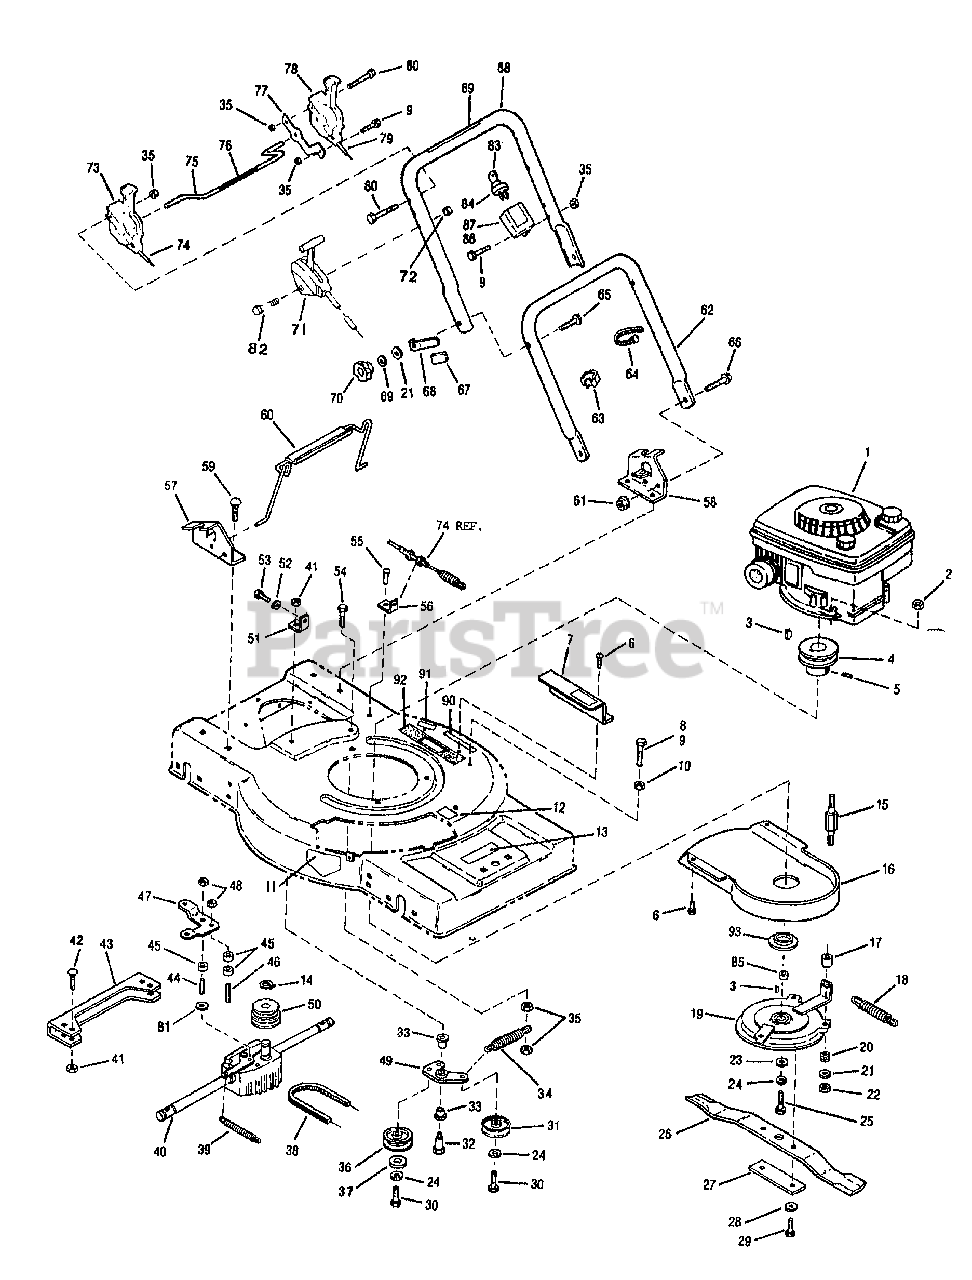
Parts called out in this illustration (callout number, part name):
1	ENGINE, B&S, 4HP MODEL 110707 STANDARD START
1	ENGINE, B&S, 4HP MODEL 110708 ELECTRIC START
2	NUT-FLANGE 5/16-18
3	KEY-WOODRUFF .156X.625
4	SHEAVE-ENGINE
5	SCR-SQHD 1/4-20X1/2 GR5
6	SCR-HW M10-24X.5 STH
7	COVER-SPRING ELEC. START
7	SPRING-CVR STD START
8	NUT-LK 1/4-20
9	SCR-HH 1/4-20X1.25
10	NUT-LK 1/4-20
11	DECAL-BLADE WARNING
12	DECAL-CAUTION
13	DECAL-CUTTING HEIGHT
14	RING, RETAINING
15	BOLT-SHOULDER-GR. 5
16	COVER-IDLER
18	SPRING-EXTENSION
20	SPRING-COIL
21	WASHER-.88X312X.08
22	NUT-H/LK 5/16-18
23	WASHER-FLAT 3/8 SAE
24	WASHER-LK .375
25	SCR-SKT HD 3/8-24X1.5 GR8
26	BLADE-VACUCUT
27	PLATE-LOCK
28	WASHER-LK .312 PYRAMIDAL (CONCAVE)
29	SCR-HFLK 5/16-18X.75
30	SCR-HH 3/8-16X1.25
31	IDLER-V
32	BOLT-SHLDR 5/16-18X.58
33	BUSHING-.5X.21 NYLON FLNG
34	SPRING-EXTENSION
35	NUT-LK 1/4-20
36	IDLER-FLAT
37	WASHER-FLAT 3/8 SAE
38	BELT-V (VACU-CUT) (33.87)
39	SPRING, EXTENSION
40	TRANSMISSION
41	NUT-HFLK 5/16-18
42	BOLT, CARRIAGE, 5/16-18 x 1-3/4" GR5
43	CHANNEL-REAR AXLE
44	STUD-THRD SHORT 10-24X1.00 G5
46	STUD-THRD LONG
47	TRANSMISSION-BRACKET
48	NUT-HEX M10-24
49	ASSM-ARM IDLER
52	WASHER-LK .25
53	SCR-HH 1/4-20X.625 G5
54	SCR-HH 1/4-20X1.0
55	RIVET-POP 3/16"DIA
56	BRACKET-CABLE
57	BRKT-HANDLE RH
58	BRKT-HANDLE LH
59	SCR-CARR 5/16-18X.62 G2
60	SUPPORT-FRONT
61	NUT-HFLK 3/8-16
62	HANDLE-LOWER
63	CLIP-WIRE
64	TIE-RED
65	SCR-CURVED HD 5/16-18X2.0
66	SCR-HFLK 3/8-16X1.00
67	GRIP-VACUCUT
68	BAG-LOCATOR
69	WASHER-LK .312
71	CONTROL, THROTTLE
72	NUT-HEX 1/4-20
73	CONTROL-BLADE LEVER
74	CONTROL-BLADE CABLE
75	RELEASE-LEVER CONTROL
76	DECAL-DRIVE CONTROL
77	PLATE-MOUNTING
78	LEVER-CONTROL DRIVE
79	CABLE-CONTROL DRIVE
80	SCR-HH 1/4-20X2.25
81	WASHER-#10
83	KEY-IGNITION (ELECTRIC START)
84	SWITCH,IGNITION (ELECTRIC START)
85	SPACER-CLUTCH
86	DECAL-KEY SWITCH
87	SUPPORT, SWITCH (ELECTRIC START)
88	HANDLE-UPPER
89	DECAL-CAUTION
90	DECAL-HEIGHT ADJUSTMENT
91	DECAL-STOP
92	PAD-RUBBER
93	SHIELD-DUST
